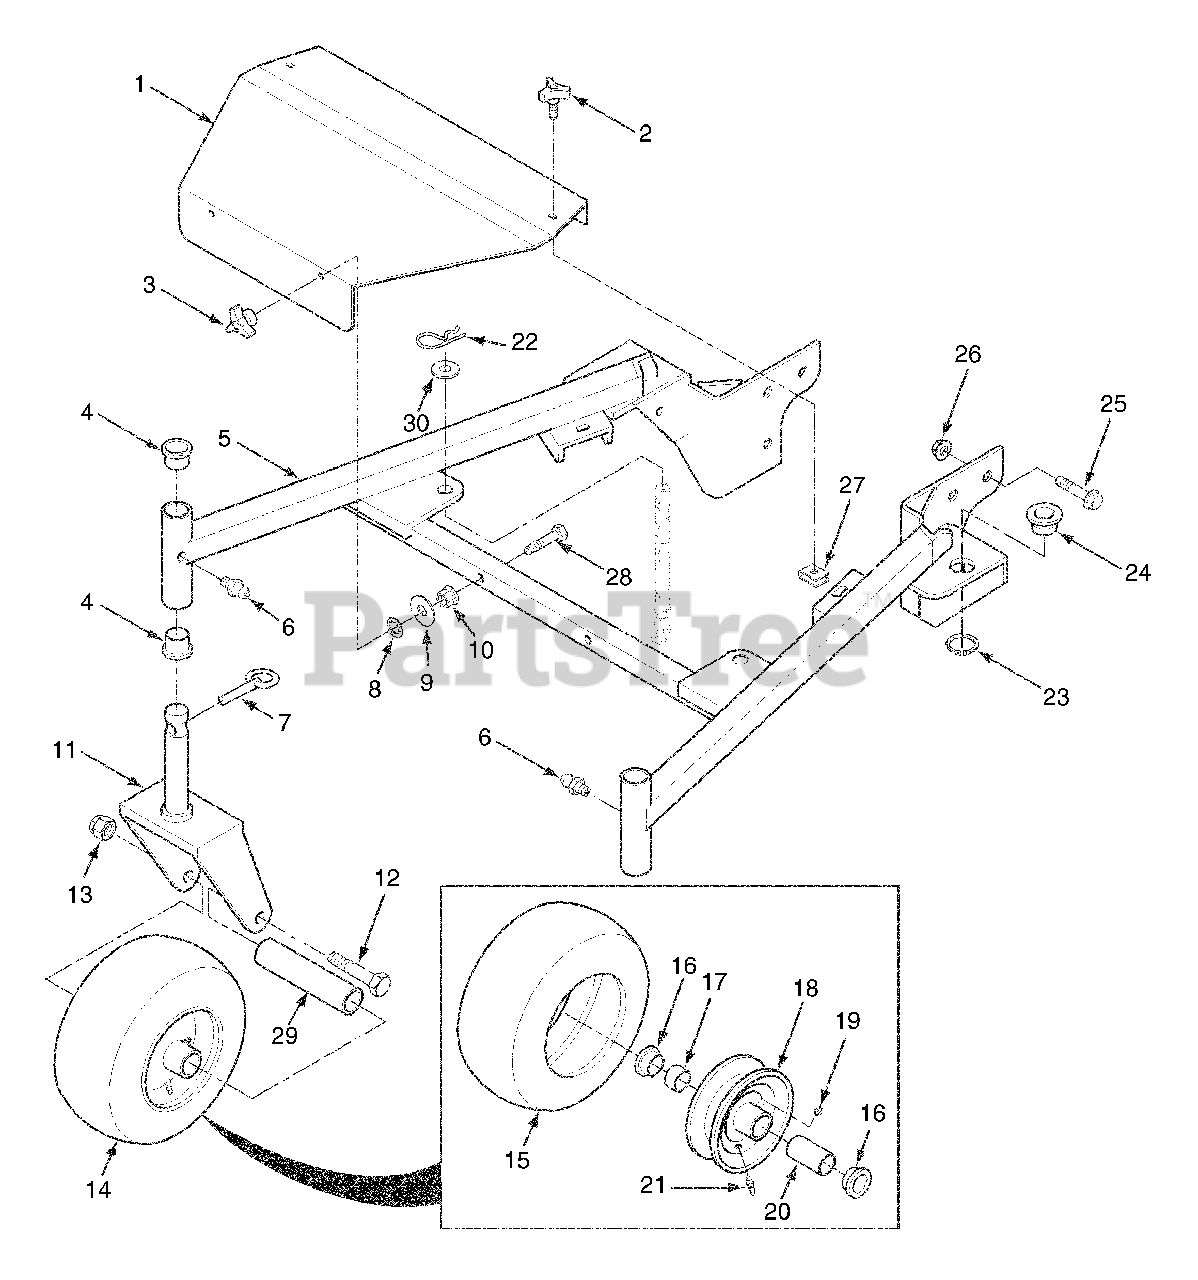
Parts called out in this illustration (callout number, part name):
1	48" Belt Cover With Decal
2	Knob With Stud
3	Knob, Deck Cover Mounting
4	Bushing, Caster
5	Frame Weldment,
6	Grease Fitting Str. 1/4-28 Self Tap
7	Quick Pin, .438" Dia.
8	Nut, Push-On - 3/8" Dia.
9	Flatwasher, 3/8" (.391 x .938 x .105)
10	Nut, 3/8-16 Serrated Flange Hex Head
11	Yoke, Caster Wheel
12	Capscrew, Hex Head 1/2-13 x 6-1/2"
13	Locknut, 1/2-13 Elastic Stop
14	Wheel Assembly, Caster
15	Tire, 11 x 4.00-5
16	Retainer
17	Roller Bearing
18	Rim, 5" x 2-3/4"
19	Grease Fitting Str.1/4-28
20	Roller Bearing .625 x 3.25"
21	Tire Valve, Purchase Locally
22	Hair Pin Cotter, .177 x 3-1/4"
23	Retaining Ring 1.50 Ext.
24	Bushing, Deck Adjustment Pin
25	Capscrew,
26	Nut, 1/2-13 Spiralock
27	U-Nut, 3/8-16
28	Capscrew, Hex Head 3/8-16 x 2-1/4"
29	Sleeve, Caster Wheel
30	Flatwasher, 5/8" - (.688 x 1.75 x .134)
